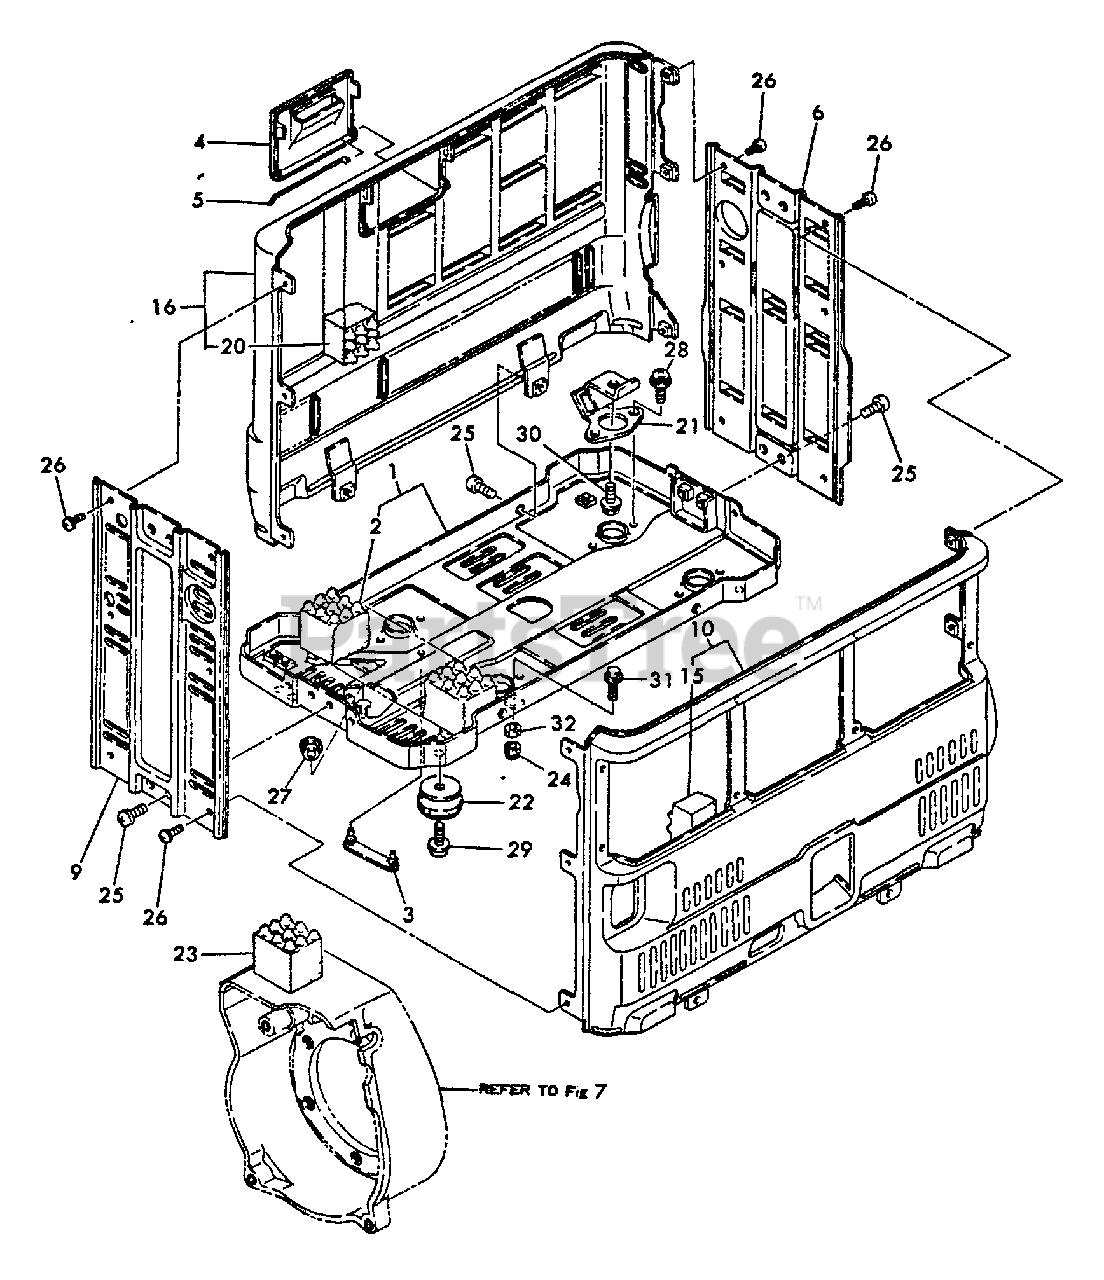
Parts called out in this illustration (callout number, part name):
1	CASE BOTTOM
2	URETHANE FOAM (E)
3	HOLDER, TOOL
4	PLUG, BLIND
5	SPRING, HINGE
6	SIDE CASE ASSY, RIGHT
9	CASE, SIDE - LEFT
10	CASE ASSY, FRONT
15	URETHANE FOAM (C)
16	CASE ASSY, REAR
20	URETHANE FOAM (D)
21	DAMPER (A)
22	DAMPER (B)
23	URETHANE FOAM (B)
24	NUT, EARTH
25	SCREW M6×10
26	SCREW M4×8
27	GROMMET
28	SCREW 6×12
29	SCREW 6×12
30	BOLT - 8×14 -- PLATED
31	BOLT - 6×16 -- PLATED
32	LOCKNUT - 6 -- PLATED
